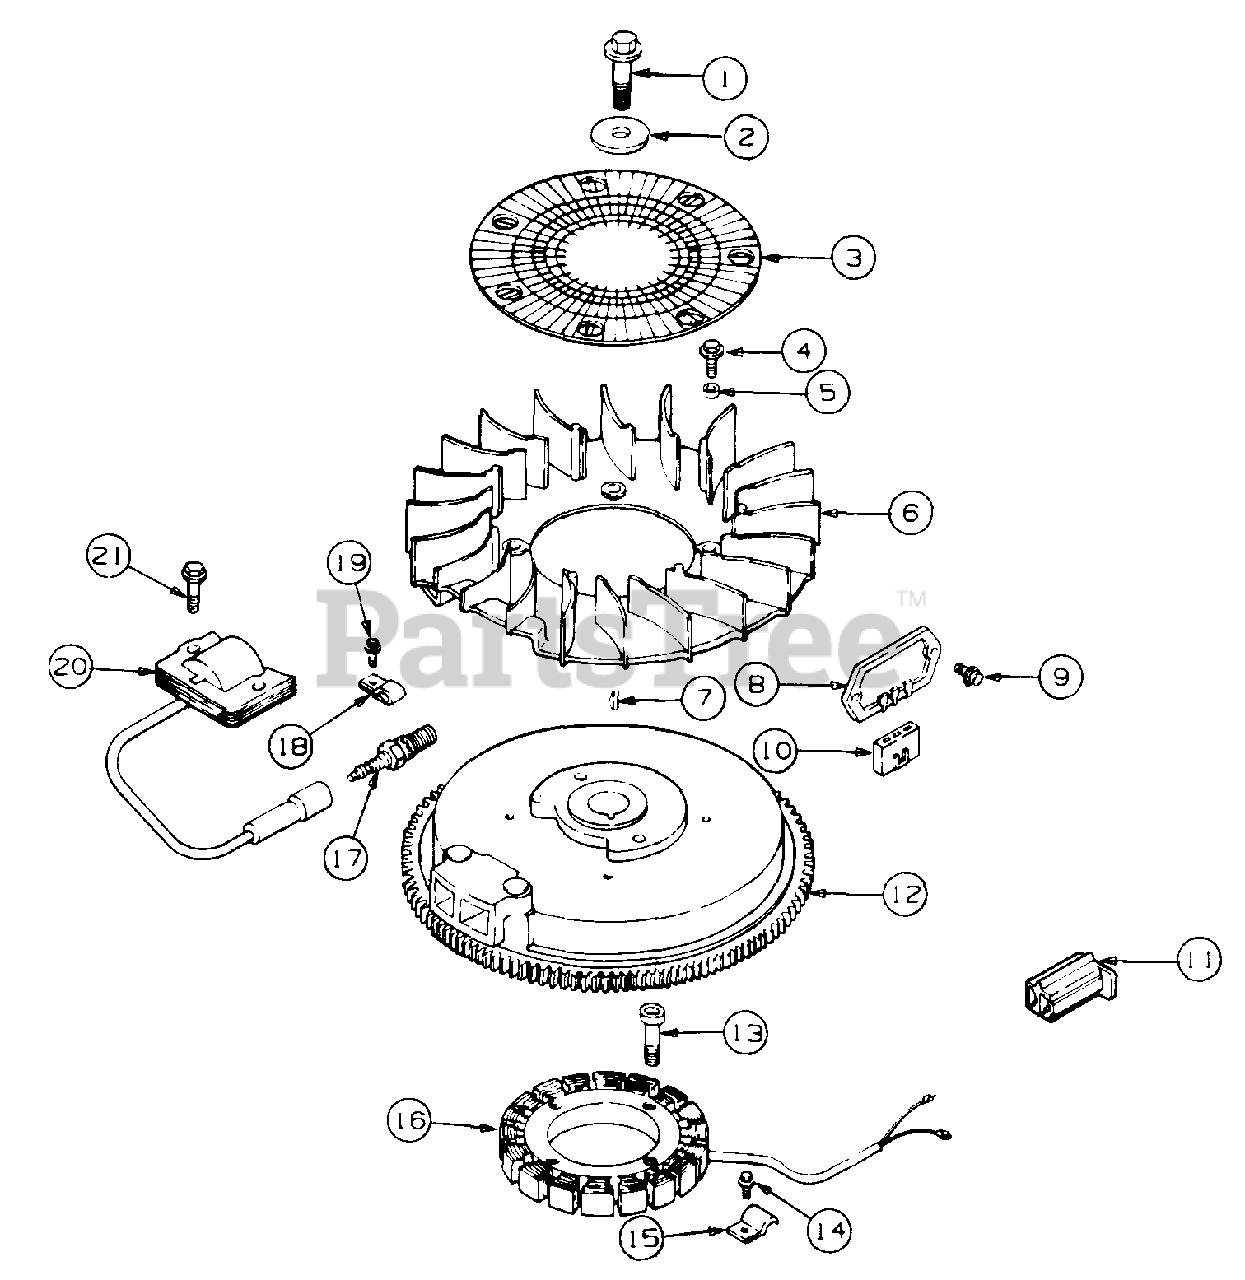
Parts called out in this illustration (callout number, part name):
1	Screw, Flywheel Mounting
2	Washer, Flywheel Screw
3	Screen, Grass
4	Screw, Fan Mounting
5	Spacer, Fan
6	Fan
8	Rectifier, Unregulated
9	Screw, Rectifier Mounting
10	Connector (3 contact)
11	Connector (2 contact)
12	Flywheel Assy
13	Screw, Stator Mounting
14	Screw, Wire Clip
15	Clip, Stator Wire
16	Stator
17	Spark Plug
18	Clip, Kill Lead
19	Screw, Lead Clip
20	Module, Ignition
21	Screw, Ignition Module, M5 X 0.8 X 20
